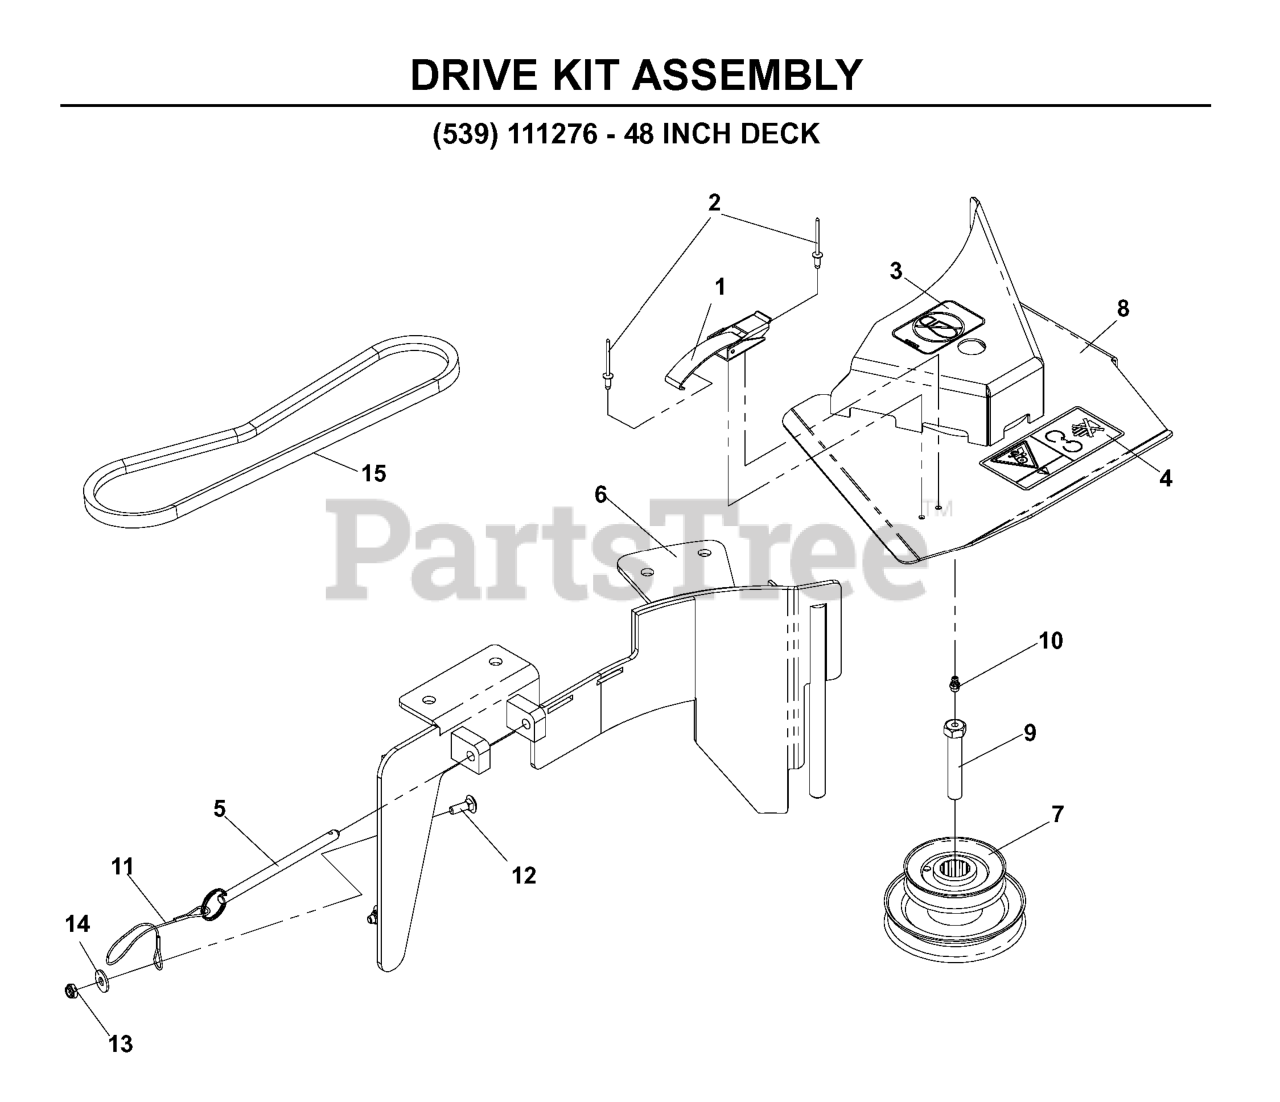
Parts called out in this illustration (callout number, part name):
1	DRAW LATCH
2	RIVET, BLIND, 5/32 DIA
3	DECAL, NO STEP
4	DECAL, BELT DRIVE
6	BLOWER DECK PLATE
7	42/48 LG DBL HEX STACK PULLEY
8	BELT SHIELD ASSY 48"
9	DRILLED BOLT 7/16-20 X 2 1/2"
10	ZERK
12	RHSNB 1/4C X 3/4
13	WASHER 1/4 FLAT
14	JAM NUT 1/4C (2 2 PW01)
